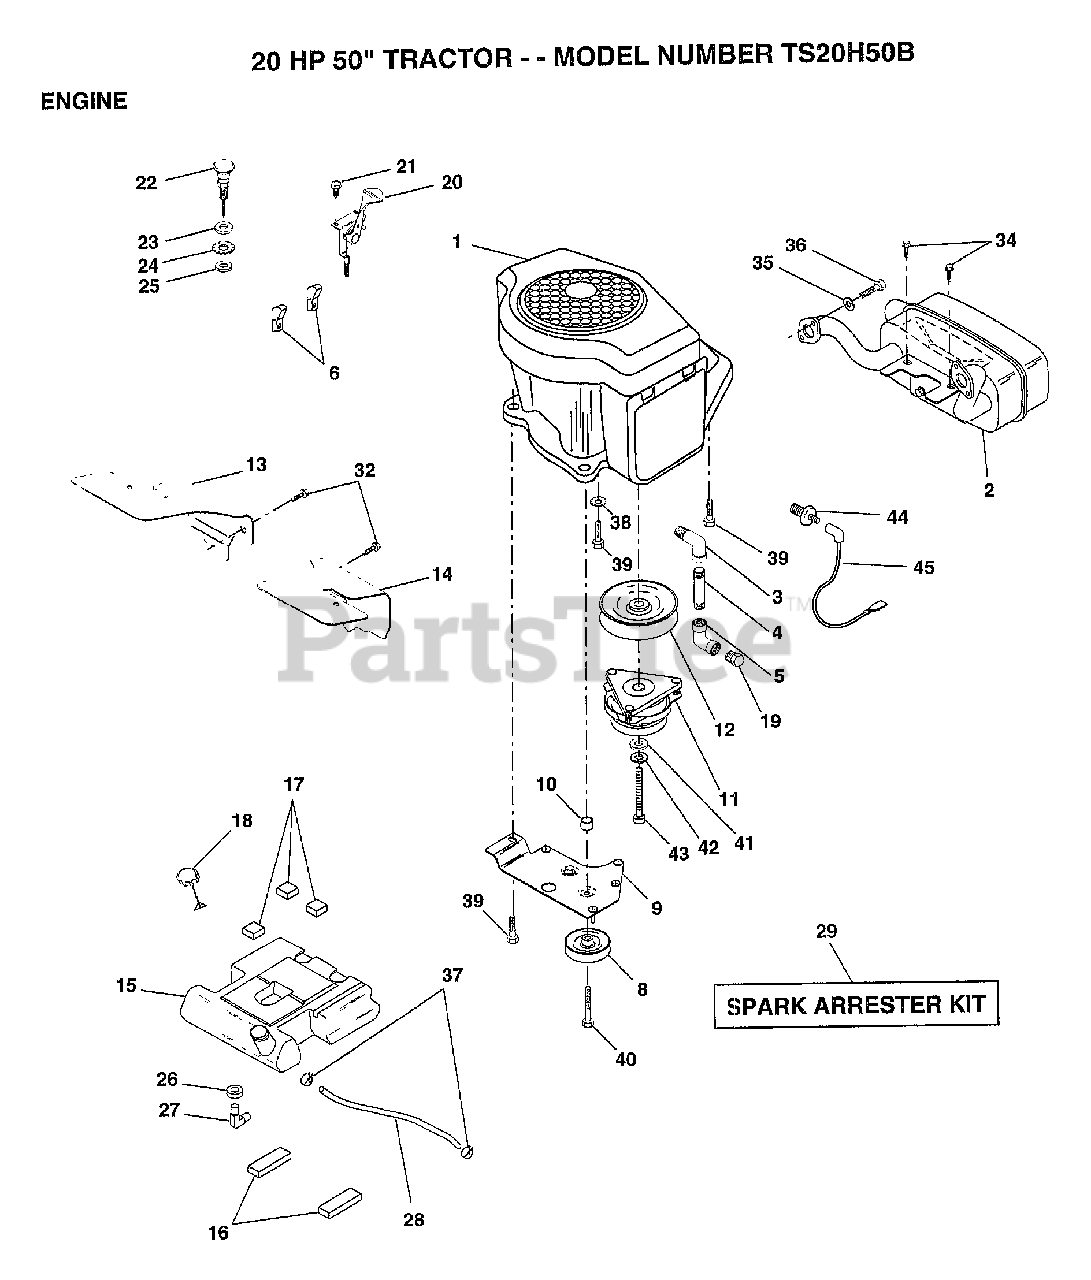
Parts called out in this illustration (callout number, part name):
2	MUFFLER.KOH.VCT.
3	STREET ELBOW LT
4	PIPE NIPPLE
5	ELBOW
6	CLAMP.TUBE.DBL.EN
10	BUSHING.
12	PULLEY.ENGINE.VGT
13	BAFFLE.AIR.LH.K
16	PAD IDLER TI
17	PAD-SPACER LT
18	CAP ASM FUEL
19	PLUG T
20	CONTROL THTL 37
21	SCREW LT
22	"CONTROL.CHOKE.51"""
23	WASHER
24	LOCKWASHER
26	BUSHING OUTLET T
27	STEM.TANK.FUEL
29	SPARK ARREST KIT
32	SCREW LT
34	SCREW
35	LOCKWASHER
36	SCREW
37	HOSE CLAMP
38	LOCKWASHER
39	SCREW LT
40	SCREW.3/8-16X3.25
41	WASHER
42	LOCKWASHER
44	SWITCH OIL KOHLER
45	WIRE LEAD KOHLER
